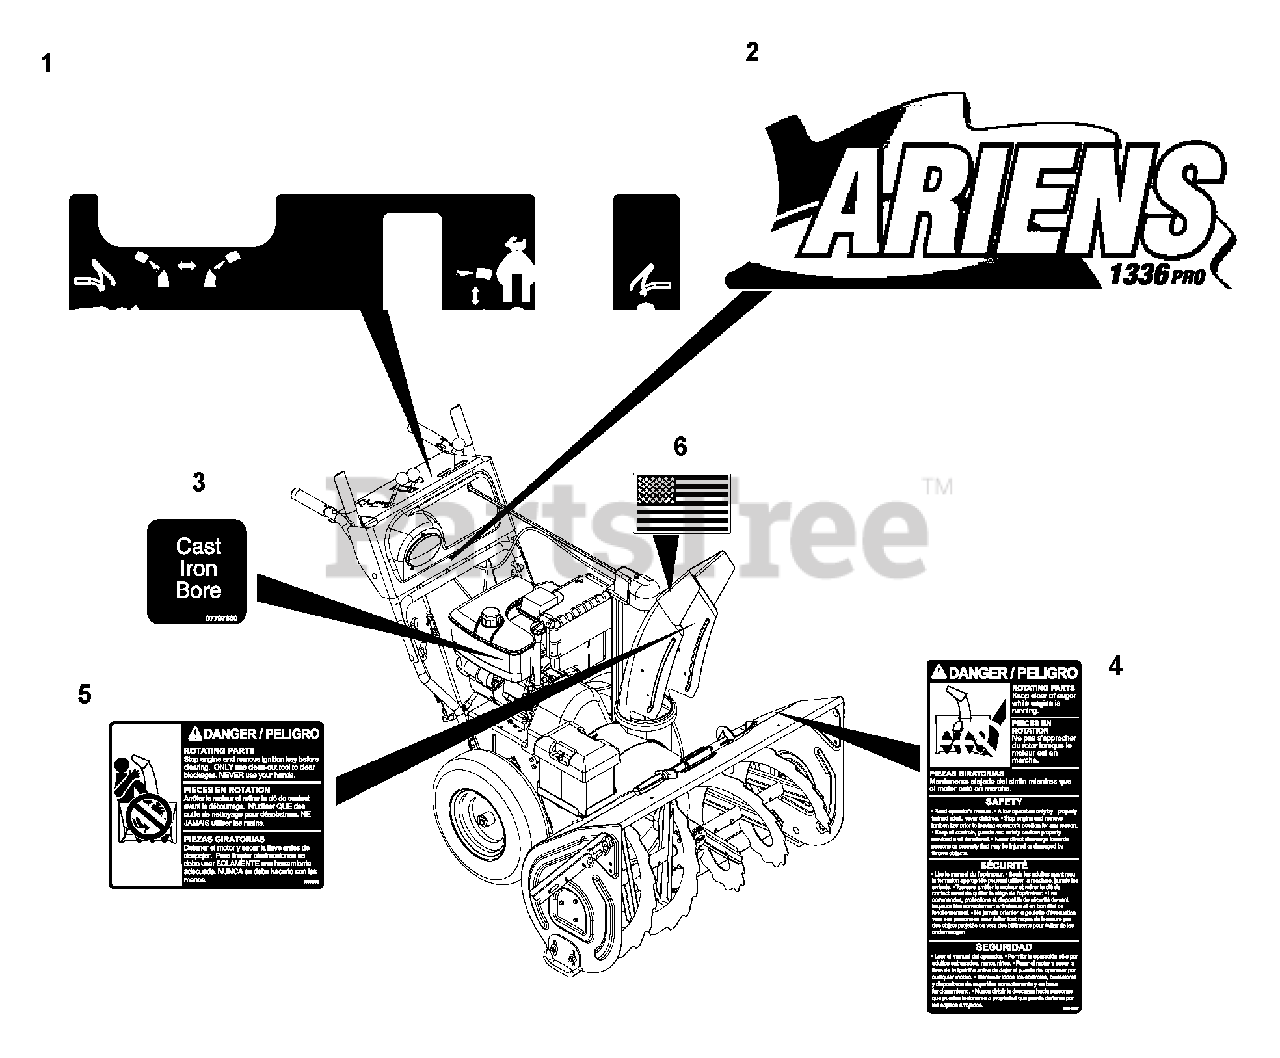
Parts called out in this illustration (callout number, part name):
1	DECAL, CONTROL
2	DECAL, FRONT DASH-926LE
3	DECAL - CAST IRON BORE
4	DECAL, DANGER
5	DECAL, DANGER - ROT. PARTS
6	DECAL, AMERICAN FLAG
